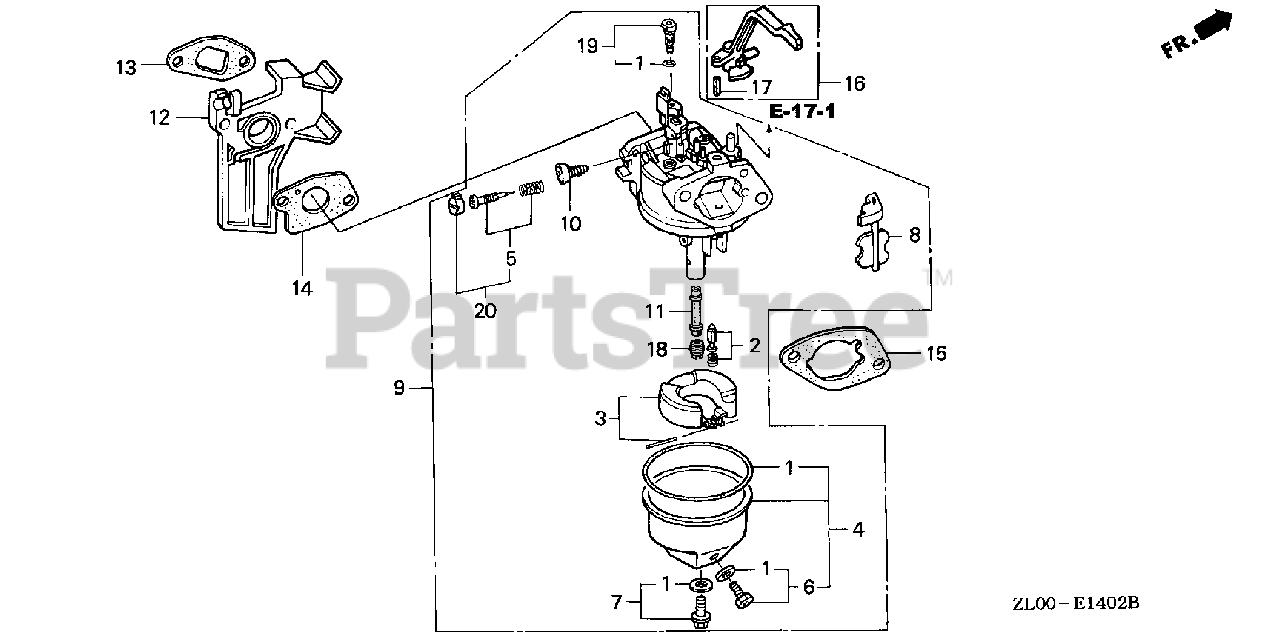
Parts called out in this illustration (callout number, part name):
1	GASKET SET
2	VALVE SET, FLOAT
3	FLOAT SET
4	CHAMBER SET, FLOAT
5	SCREW SET, PILOT
6	SCREW SET, DRAIN
7	SCREW SET B
8	CHOKE SET
9	CARBURETOR ASSY. (BE74A A) (BE74A B)
10	SCREW, THROTTLE STOP
11	NOZZLE, MAIN
12	INSULATOR, CARBURETOR
13	GASKET, INSULATOR
14	GASKET, CARBURETOR
15	GASKET, AIR CLEANER
16	LEVER, CHOKE
17	PIN, SPRING (2X12)
18	JET, MAIN (#72)
18	JET, MAIN (#75)
18	JET, MAIN (#78)
19	JET SET, PILOT (#40)
